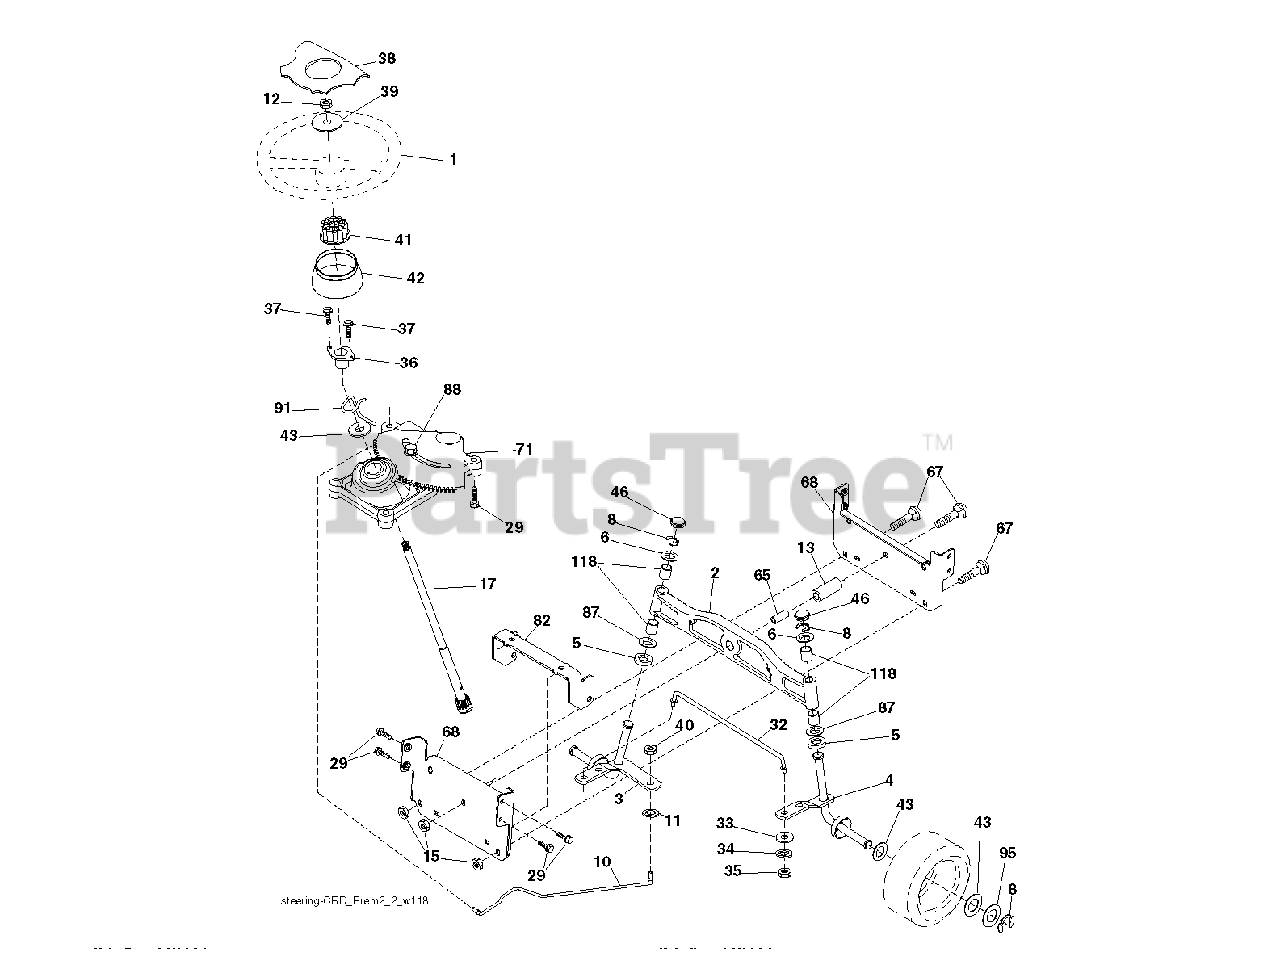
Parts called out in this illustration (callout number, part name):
1	WHEEL.STEERING.STDSRR.BLK/OV
2	AXLE.ASM.LT.CAST.LGHTWGHT
3	SPINDLE.ASM.LH.15"TIRES
4	SPINDLE.ASM.RH.15"TIRES
8	RING CLIP
10	DRAGLINK.15".TIRES.2001
11	WASHER, LOCK 3/8
12	NUT.HEX.1/2-20
13	TUBE, PIVOT AXLE
15	NUT
17	SHAFT ASM STRG
29	SCREW, 3/8-16X3/4
33	WASHER M
34	LOCKWASHER
35	NUT, CROWNLOCK
36	BUSHING, STRG. BLK
38	CAP.WHL.STRNG.STDSRRD.SRS.BLK
39	WASHER 9/16"ID, 2 3/8"OD
40	NUT CROWNLOCK 3/8-24
41	ADAPTER, WHEEL STNG..
42	BOOT.STEERING.
46	CAP.SPINDLE
65	SPACER.BRACE.AXLE
67	BOLT CARRIAGE
68	BRACE.AXLE.15"TIRES
71	STEERING ASM
82	BRACKET.SUSP.CHASSIS.FRONT.15
87	WASHER, FLAT .781 X 1 1/2"
88	BOLT, SHOULDER 7/16-20
91	CLIP.STEERING
95	WASHER.HARDENED
118	BUSHING, AXLE CAST
